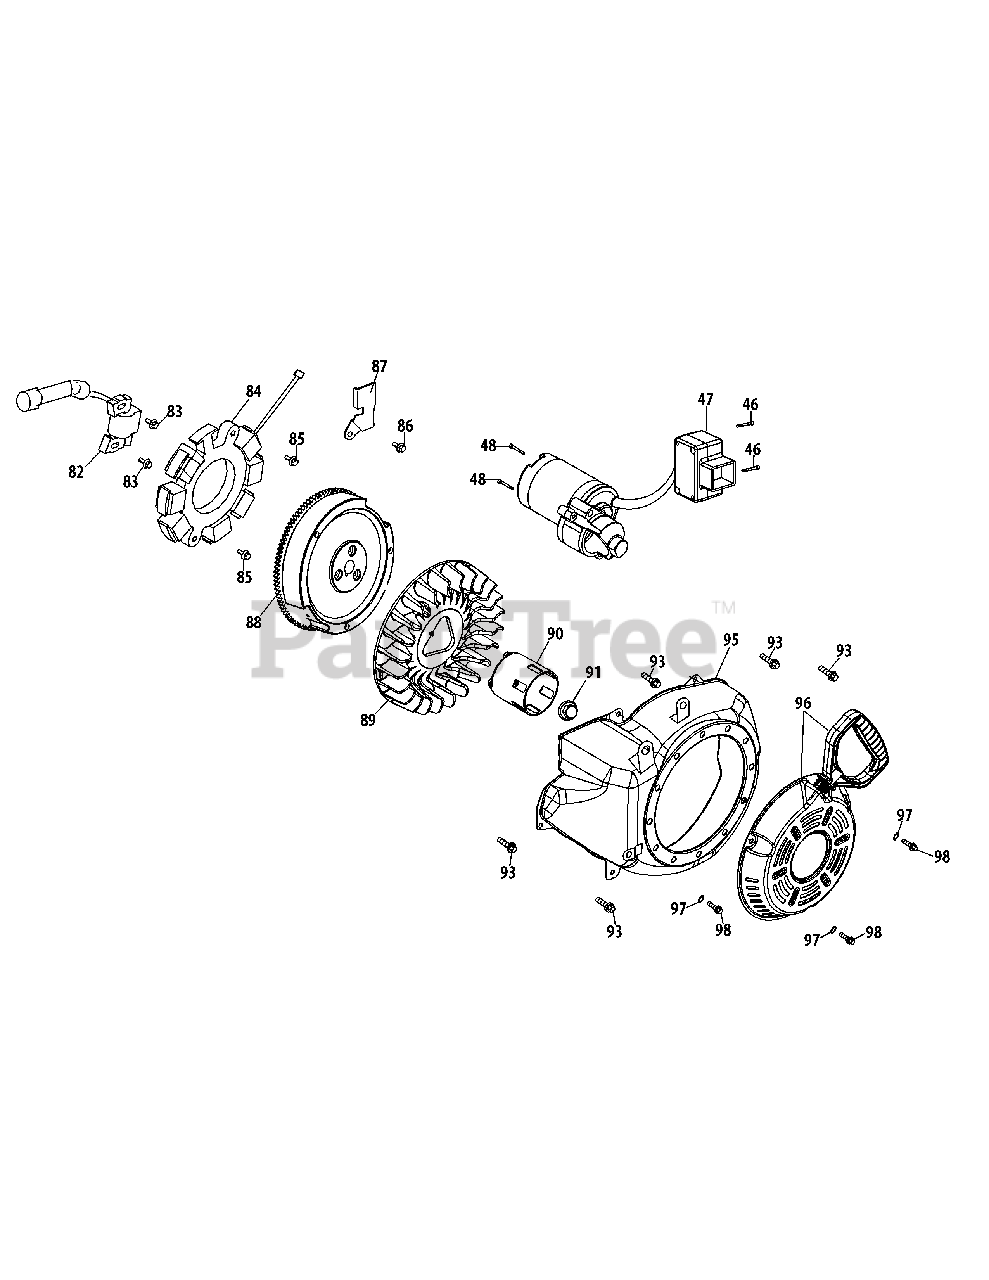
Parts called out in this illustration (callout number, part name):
46	Bolt M4×55
47	Electric Starter
48	Bolt M8×55
82	Ignition Coil Assembly
83	Ignition Coil Bolt
84	Coil Assy.Charge
85	Bolt M6×30
86	Bolt M6×8
87	Alternator Wire Clamp Brkt
89	Fan,Cooling
90	Pulley,Starter
91	Nut,Special M16×1.5
92	Bolt M6×16
93	Bolt M6×12
95	Blower Housing
96	Recoil Starter
97	Gasket 6
98	Bolt M6×10
